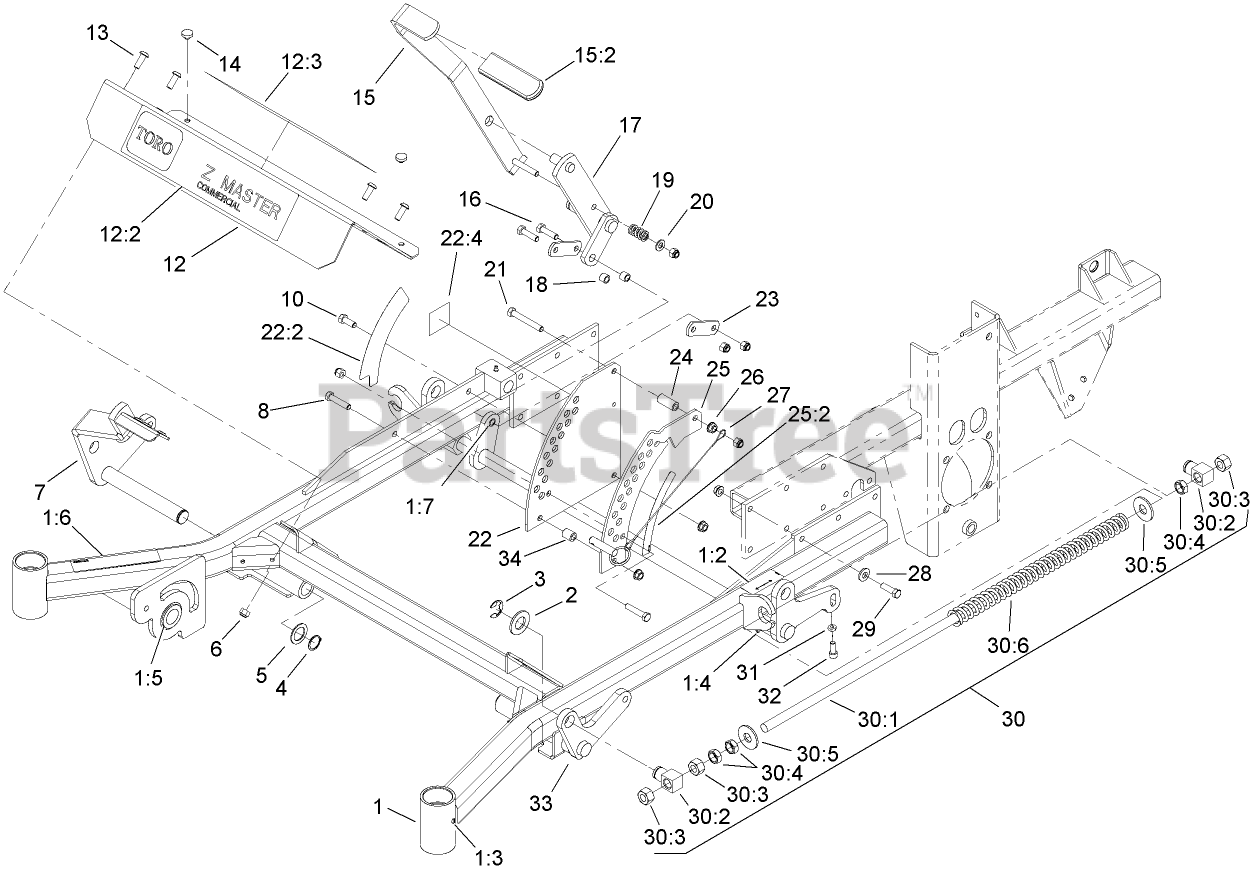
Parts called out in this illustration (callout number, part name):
1	FRAME ASM
1:2	DECAL-BRAKE, PARKING
1:4	FITTING-GREASE
1:5	BUSHING
1:6	DECAL-WARNING
1:7	Bushing
2	WASHER-FLAT
3	RING-RETAINING, EXT
4	RING-RETAINING
5	WASHER-SPACER
6	NUT-LOCK, NI
7	LIFT-DECK, RH FRONT
8	SCREW-HH
10	SCREW-HH
12	FOOTREST
12:3	DECAL-DANGER, SLOPE
13	SCREW-HSBH
14	BUMPER
15	LIFT LEVER/GRIP ASM
15:2	GRIP-LEVER, LIFT
16	SCREW-HH
17	ARM-LIFT, DECK
18	Bushing
19	SPRING-COMPRESSION
20	WASHER-FLAT
21	SCREW-HH
22	PLATE-DECK LIFT, OUTER (CE)
22:2	DECAL-HEIGHT, DECK
22:4	DECAL-NOISE
23	ARM-LIFT, DECK
24	BUSHING-LEVER, LIFT
25	PLATE-DECK LIFT, INNER (CE)
25:2	DECAL-HEIGHT, DECK
26	NUT-HHF, WHIZ
27	Hitch Pin ASM
28	WASHER-BELLEVILLE
29	SCREW-HH
30	Front Frame Spring ASM
30:1	ROD-LIFT, DECK
30:2	SWIVEL-DECK MOUNT, REAR
30:3	NUT-HEX
30:4	NUT-JAM
30:5	WASHER-FLAT
30:6	SPRING-SUPPORT, DECK
31	NUT-JAM
32	SCREW-HSH
33	LIFT-DECK, LH
34	BUSHING-LEVER, LIFT
